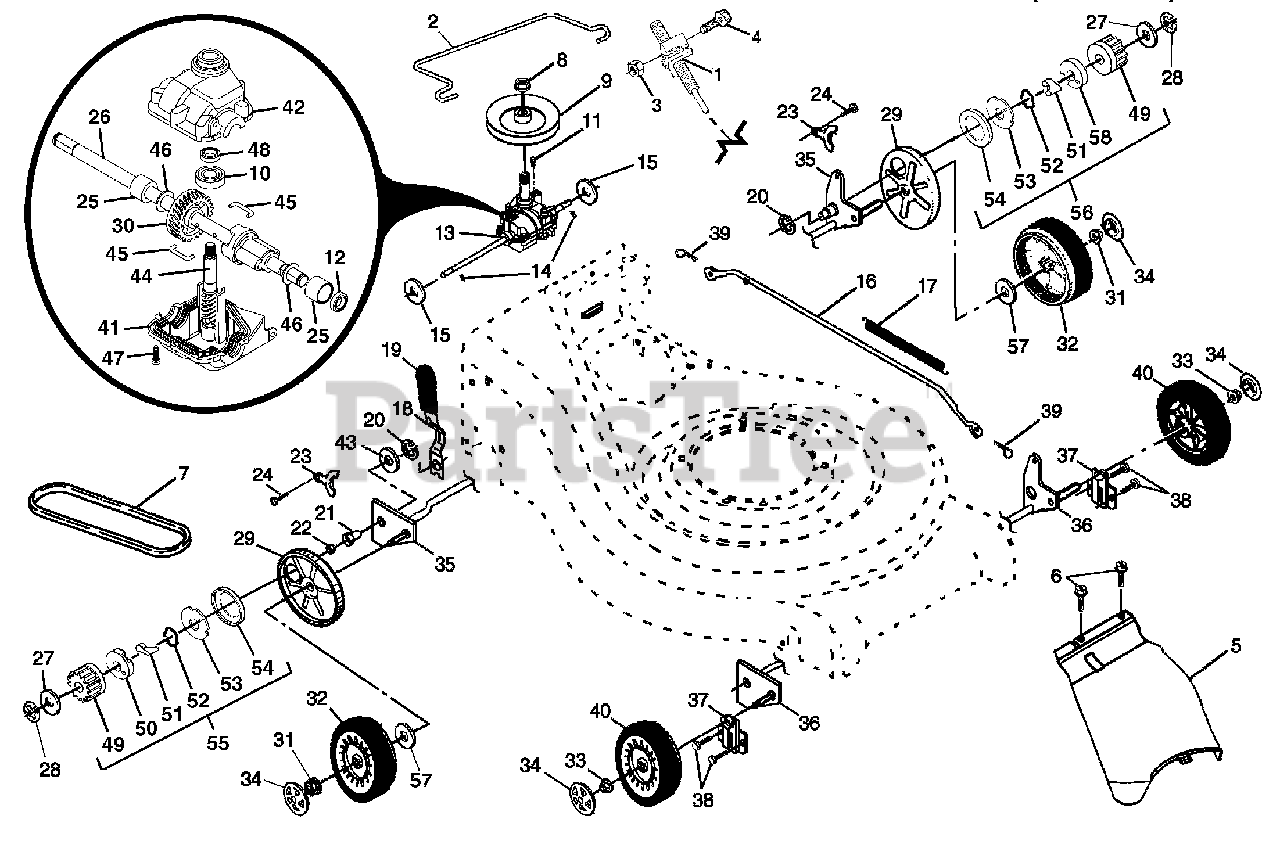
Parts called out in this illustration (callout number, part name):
1	Handle, Upper
2	Handle, Lower
3	Spring, Rear Door, RH
4	Guide, Rope, Side
5	Nut, Hex, with Lockwasher Insert 1/4-20
6	Wire, Tie
7	Bolt, Handle 5/16-18 x 2-5/8
8	Knob, Handle
9	Control Bar
10	Bolt, Carriage
11	Nut, Hex, with Lockwasher Insert 5/16-18 UNC
12	Cotter, Hairpin
13	Spring, Rear Door, LH
16	Rear Door Assembly
17	Bolt, Rear Door
18	Plug, Mulcher
19	Kit, Housing
20	Handle Bracket Asembly, Left
21	Handle Bracket Assembly, Right
22	Screw, Hex Washer Head
23	Bolt, Hex Head 5/16-18 x 5/8
24	Nut, Hex, with Lockwasher Insert 5/16-18
25	Baffle, Side
26	Screw #12 x 5/8
27	Skirt, Rear
28	Screw, Hinge 1/4-20 x 1.25
29	Cable, Engine Zone Control
31	Blade, 21"
34	Bolt, Hex Head
37	Bolt, Engine
39	Grassbag
40	Frame, Grassbag
41	Danger Decal
57	Bracket Assembly
58	Screw
59	V-Groove Pulley
61	Nut, Hex, Flanged
62	Locknut
63	Idler Arm
64	Idler Pulley
65	Shoulder Bolt
66	Rear Door Assembly
67	Mulcher Door, Multi-Cut
68	Nut, Hex
76	Bracket, Upstop
77	Screw
84	Screw
85	Key, Hi-Pro
86	Pulley
87	Washer
88	Washer, Lock
89	Blade Adapter
90	Debris Shield
91	Bolt
92	Mounting Bracket, Debris Shield
92	Operator's Manual, English
92	Operator's Manual, French
92	Repair Parts Manual, English / French
